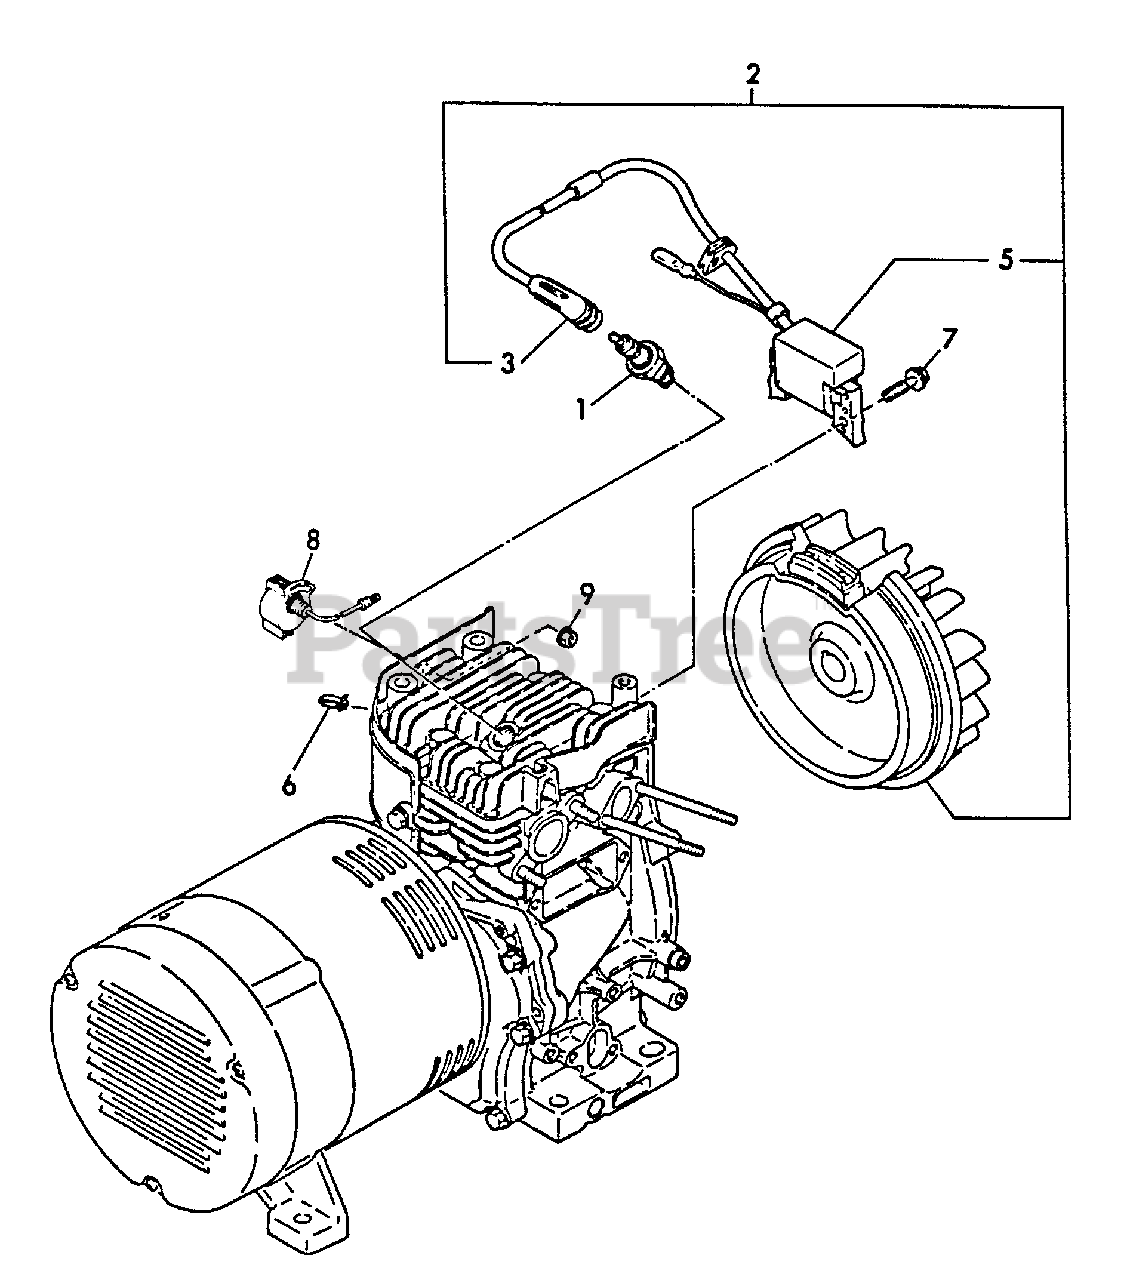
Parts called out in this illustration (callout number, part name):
1	SPARK PLUG
2	FLYWHEEL
3	CAP, PLUG
5	COIL, IGNITION
6	CLAMP
7	BOLT - 6X25
8	IGNITION SWITCH ASSY
9	NUT - 8
